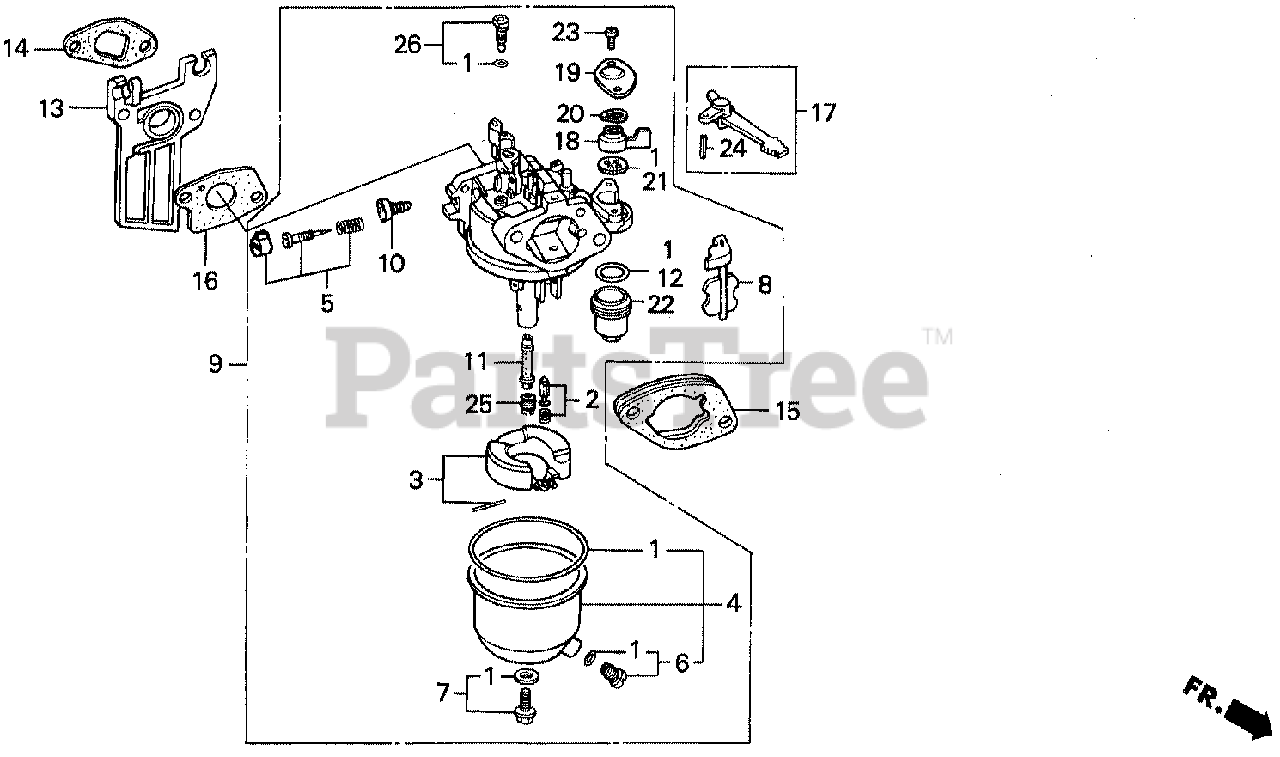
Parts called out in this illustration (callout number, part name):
1	GASKET SET
2	VALVE SET, FLOAT
3	FLOAT SET
4	CHAMBER SET, FLOAT
5	SCREW SET
6	SCREW SET, DRAIN
7	SCREW SET B
8	CHOKE SET
9	CARBURETOR ASSY. (BE65B B)
10	SCREW, THROTTLE STOP
11	NOZZLE, MAIN
12	O-RING
13	INSULATOR, CARBURETOR
14	GASKET, INSULATOR
15	SPACER, CARBURETOR
16	GASKET, CARBURETOR
17	LEVER, CHOKE (STD)
18	LEVER, VALVE
19	PLATE, LEVER SETTING
20	SPRING, VALVE LEVER
21	GASKET, VALVE
22	CUP, FUEL STRAINER
23	SCREW, PAN (3X6)
23	SCREW, PAN (3X8)
24	PIN, SPRING (2X12)
25	JET, MAIN (#65)
25	JET, MAIN (#68)
25	JET, MAIN (#70)
26	JET SET, PILOT (#35)
